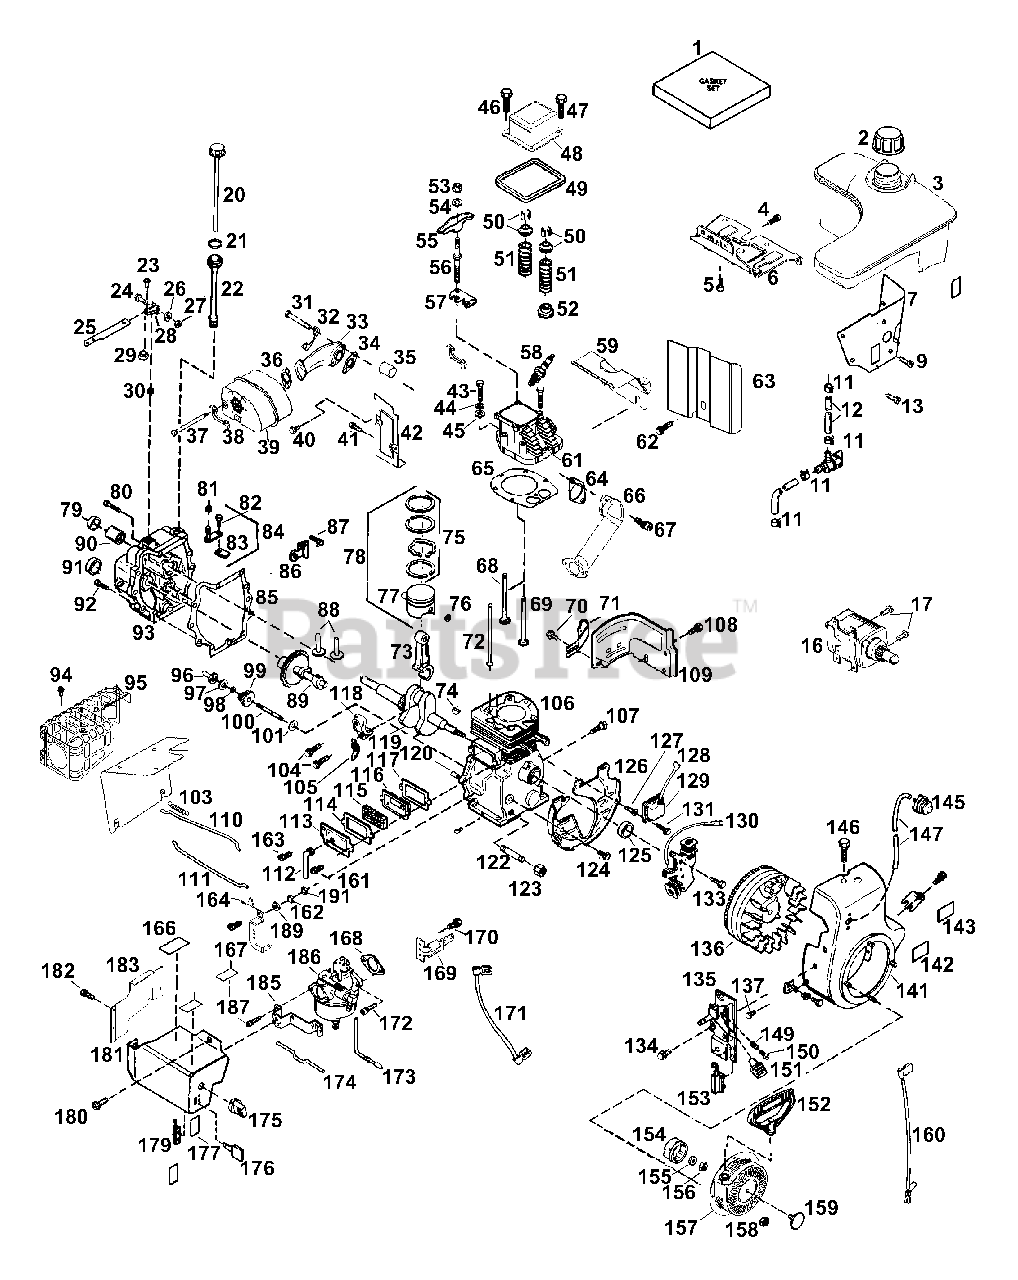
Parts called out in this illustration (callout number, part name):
1	Gasket Set
2	Fuel Cap
3	Fuel Tank
4	Screw, 5/16-18 x 7/8"
5	Screw, 1/4-15 x 3/4"
6	Fuel Tank Bracket
7	Fuel Tank Extension
9	Screw, 12-16 x 5/8"
11	Fuel Line Clamp
12	Fuel Line
13	Screw, 10-32 x 1/2"
16	Electric Starter Motor (120 Volt)
17	Screw, Torx T-30, 1/4-20 x 15/32"
22	Oil Fill Tube
23	Screw, Torx T-15, 8-32 x 3/8"
24	Screw, 10-32 x 3/4"
25	Governor Lever
26	Lock Washer
27	Lock Nut, 10-32
28	Governor Lever Clamp
29	Lock Nut, 10-32
30	Retaining Ring
31	Screw, 5/16-18 x 1-9/32"
32	Locking Plate
33	Exhaust Manifold
34	Exhaust Gasket
35	Exhaust Port Liner
36	Exhaust Gasket
37	Screw, 5/16-18 x 4 1/2"
38	Locking Plate
40	Screw, 1/4-20 x 5/8"
41	Screw, 10-24 x 9/16"
42	Blower Housing Extension
43	Screw, 5/16-18 x 2 1/2"
44	Belleville Washer
46	Valve Cover Mounting Stud
47	Screw, T-30, 1/4-20 x 1/2"
48	Rocker Arm Cover
49	Rocker Arm Cover Gasket
50	Valve Spring Keeper
51	Valve Spring
52	Intake Valve Seal
54	Lock Washer
55	Rocker Arm
56	Rocker Arm Stud
57	Push Rod Guide
58	Spark Plug (RN4C)
59	Cylinder Head Cover
61	Cylinder Head
62	Screw, 10-32 x 1/2"
63	Heat Baffle
64	Intake Pipe Gasket
65	Cylinder Head Gasket
66	Intake Pipe
67	Screw, Torx T-30, 5/16-18 x 7/8"
68	Exhaust Valve (1/32" OS)
69	Intake Valve (Std.)
70	Screw, 10-24 x 9/16"
71	Fill Tube Clip
73	Connecting Rod Ass'y
74	Flywheel Key
75	Ring Set (Std.)
76	Piston Pin Retaining Ring
77	Piston & Pin Ass'y (Std.)
78	Piston, Pin & Ring Set (.010" OS)
80	Screw, 1/4-20 x 1-3/16"
82	Screw, 6-40 x 5/16"
83	Governor Yoke
84	Governor Rod Ass'y
85	Cylinder Cover Gasket
86	Governor Gear Bracket
87	Screw, 10-24 x 1/2"
88	Valve Lifter
89	Camshaft (MCR)
90	Crankshaft Bushing
92	Screw, 1/4-20 x 1-11/16"
93	Cylinder Cover
94	Screw, 10-32 x 5/16"
95	Heat Shield
96	Governor Spool
98	Retaining Ring
99	Governor Gear Ass'y
100	Governor Shaft
103	Extension Spring
104	Connecting Rod Bolt
105	Oil Dipper
107	Screw, 1/4-20 x 1/2"
108	Screw, T-30, 1/4-20 x 1/2"
109	Blower Housing Extension
110	Governor Link
111	Throttle Link
112	Breather Tube
113	Valve Cover
114	Valve Cover Gasket
115	Breather Element
116	Breather Body
117	Valve Cover Gasket
118	Connecting Rod Ass'y
119	Crankshaft
120	Dowel Pin
122	Oil Drain Extension
123	Extension Cap
124	Screw, 1/4-20 x 5/8"
126	Blower Housing Baffle
127	Solid State Mounting Stud
128	Spark Plug Cover
129	Solid State Ignition
131	Screw, Torx T-15, 10-24 x 15/16"
133	Screw, 1/4-20 x 3/4"
134	Screw, 10-32 x 1/2"
135	Control Bracket
136	Flywheel (W/Ring Gear)
137	Screw, Torx T-40, 5/16-24 x 21/32"
141	Blower Housing
142	Primer Decal
145	Primer Ass'y
147	Primer Line
149	Compression Spring
150	Screw, Torx T-10, 5-40 x 7/16"
151	Control Knob
152	Starter Handle
154	Starter Cup
155	Lock Washer
156	Flywheel Nut
157	Rewind Starter
158	Nut & Lock Washer, 1/4-28
159	Starter Decal
160	Ground Wire
161	Screw, 10-24 x 1/2"
163	Screw, T-30, 1/4-20 x 27/32"
164	Bellcrank Lever
166	Warning Decal
167	Caution Decal
168	Carburetor To Intake Pipe Gasket
169	Key Switch Bracket
170	Screw, 10-32 x 23/64"
171	Ground Wire
172	Screw, Torx T-30, 1/4-20 x 27/32"
173	Choke Rod
174	Choke Spring
175	Choke Knob
176	Key Switch
177	Throttle Decal
180	Screw, 10-32 x 1/2"
181	Carburetor Cover (Front)
182	Screw, 10-32 x 1/2"
183	Carburetor Cover
185	Choke Bracket
186	Carburetor
187	Screw, 10-32 x 1/2"
